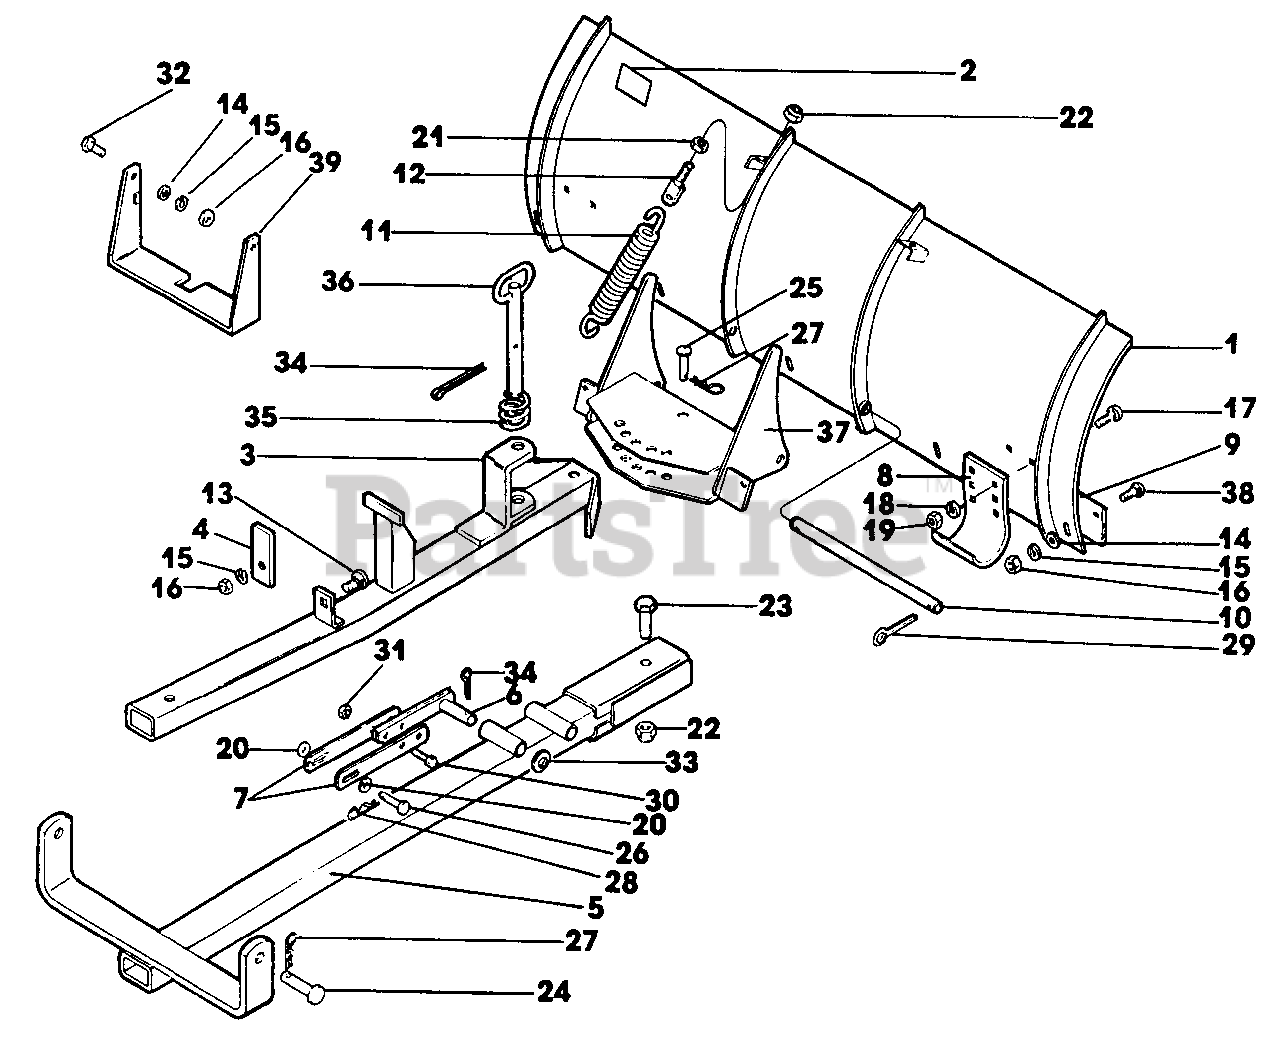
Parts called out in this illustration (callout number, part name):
1	Dozer Blade Assembly. w/Decal
2	Safety Decal
3	Front Frame Assembly
4	Frame Stop
5	Rear Frame Assembly
6	Lift Link Assembly
7	Reversing Link
8	Shoe
9	Scraper Blade
10	Trip Pin
11	Spring
12	Spring Adjuster Bolt
13	Bolt, Wafer Hd. Short Neck
14	Washer, Flat
15	Washer, Lock
16	Nut, Hex
17	Bolt, Carriage
18	Washer, Lock
19	Nut, Hex
20	Washer, Flat
21	Nut,HexJam
22	Nut, Hex Cone Lock
23	Cap Screw, Hex Hd
24	Clevis Pin
25	Clevis Pin
26	Clevis Pin
27	Spring Clip
28	Spring Clip
29	Pin, Cotter
30	Cap Screw, Hex Hd
31	Nut, Hex
32	Cap Screw, Hex Hd
33	Washer, Flat
34	Pin, Cotter
35	Spring
36	Hitch Pin Assembly
37	Trip Plate Assembly
38	Bolt Carriage
39	Stabilizer Saddle Assembly
